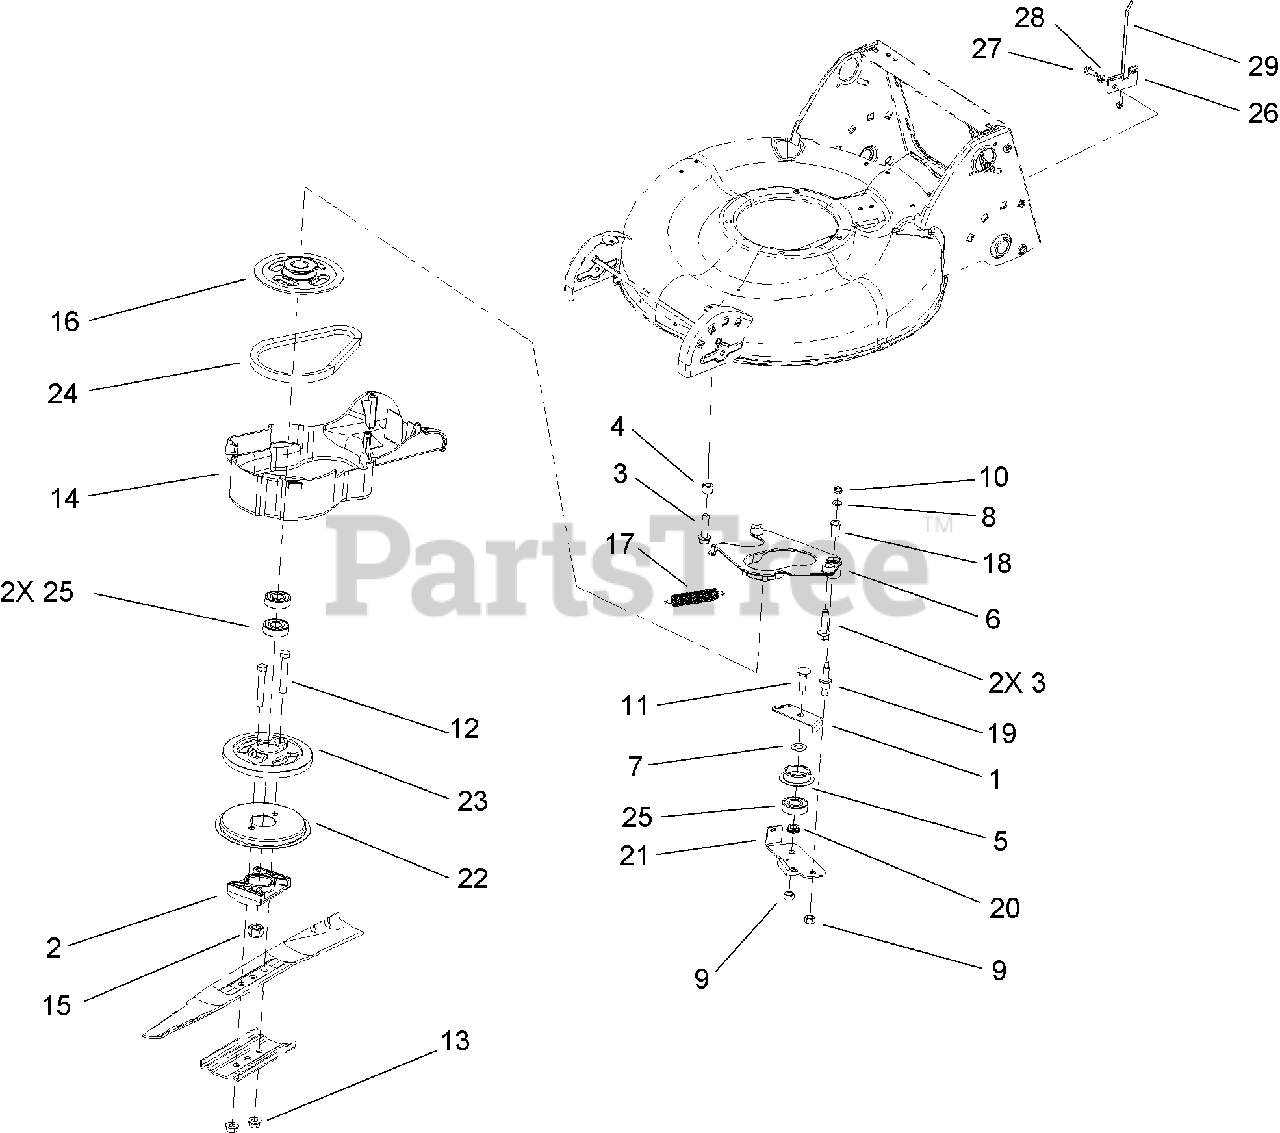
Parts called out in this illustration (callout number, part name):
1	PLATE-GUIDE
2	SUPPORT-BLADE
3	SCREW-HWH
4	TUBE-SPACER
5	RETAINER-BELT
6	PLATE-ANCHOR
8	WASHER-FLAT
10	NUT-LOCK, NI
11	SCREW-CARR
12	SCREW-HH
13	NUT-LOCK
14	COVER-BBC
16	PULLEY-BBC
17	SPRING-TENSION, BRAKE
19	BOLT-SHOULDER
20	SPACER-BEARING
21	BRAKE ARM ASM
22	DISC
23	DRUM
25	BEARING-BALL
26	CLAMP-CABLE, BBC
27	SCREW-HH
28	WASHER-LOCK
29	STRAP-TIE
